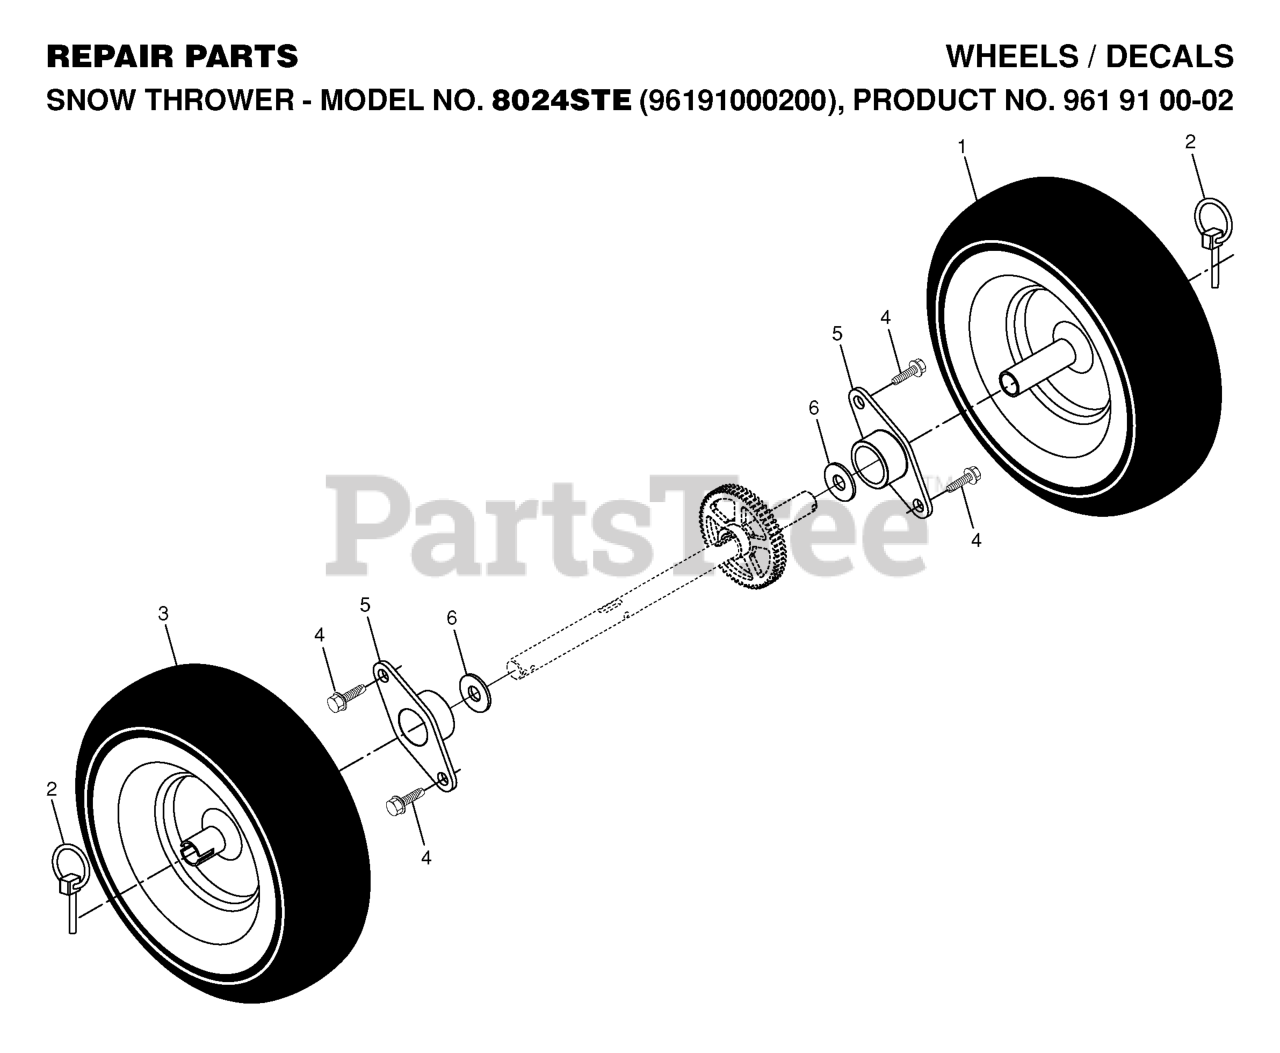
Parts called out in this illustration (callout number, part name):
1	WHEEL.ASM.LT.16"GRY.XTRAC
2	PIN KLIK, 1/4
3	WHEEL.ASM.RT.16".GRAY.SN
5	BEARING, AXLE
6	WASHER TRUST 1"
